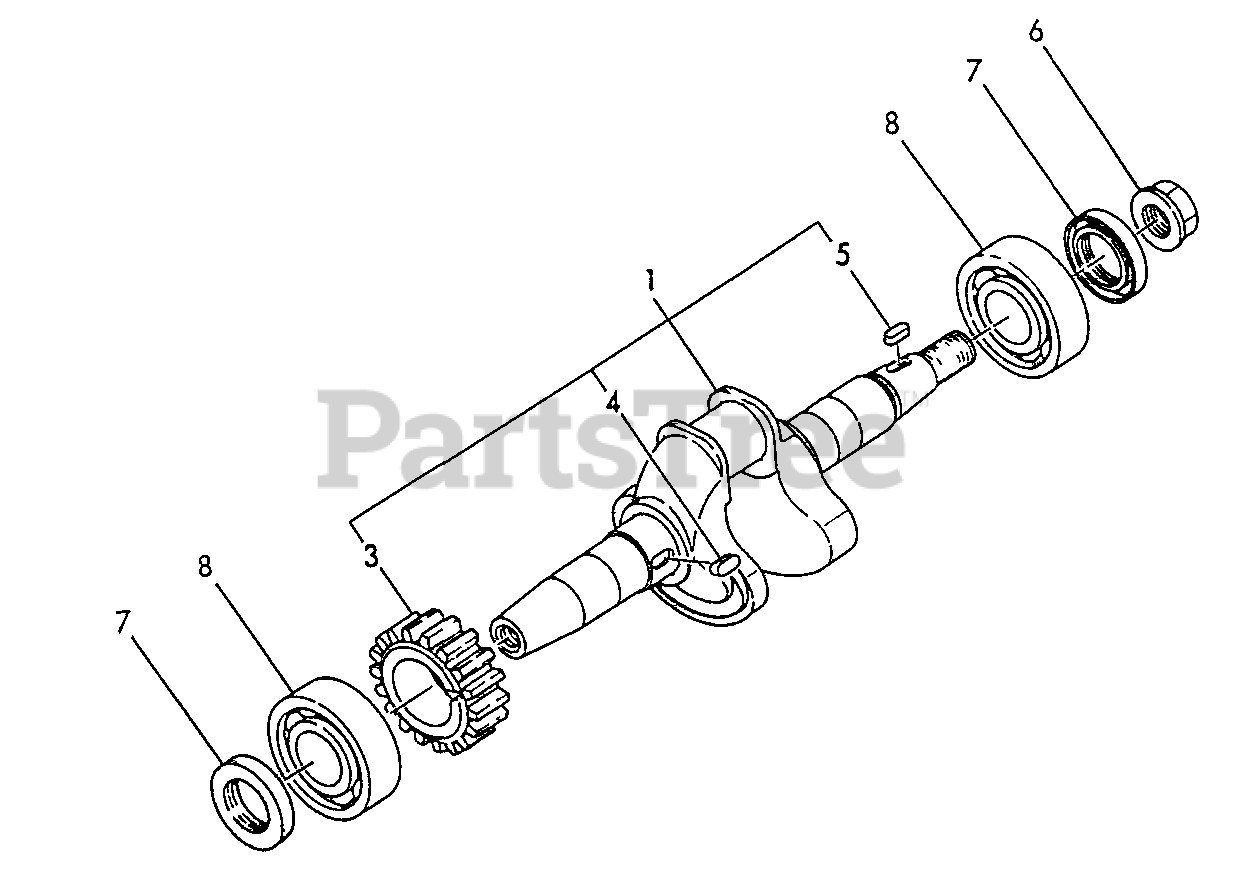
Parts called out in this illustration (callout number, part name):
1	CRANKSHAFT ASSY
3	GEAR, CRANKSHAFT
4	KEY - 4X10
5	KEY - 4X10
6	NUT - 12
7	SEAL, OIL
8	BEARING, BALL - 6204C3
